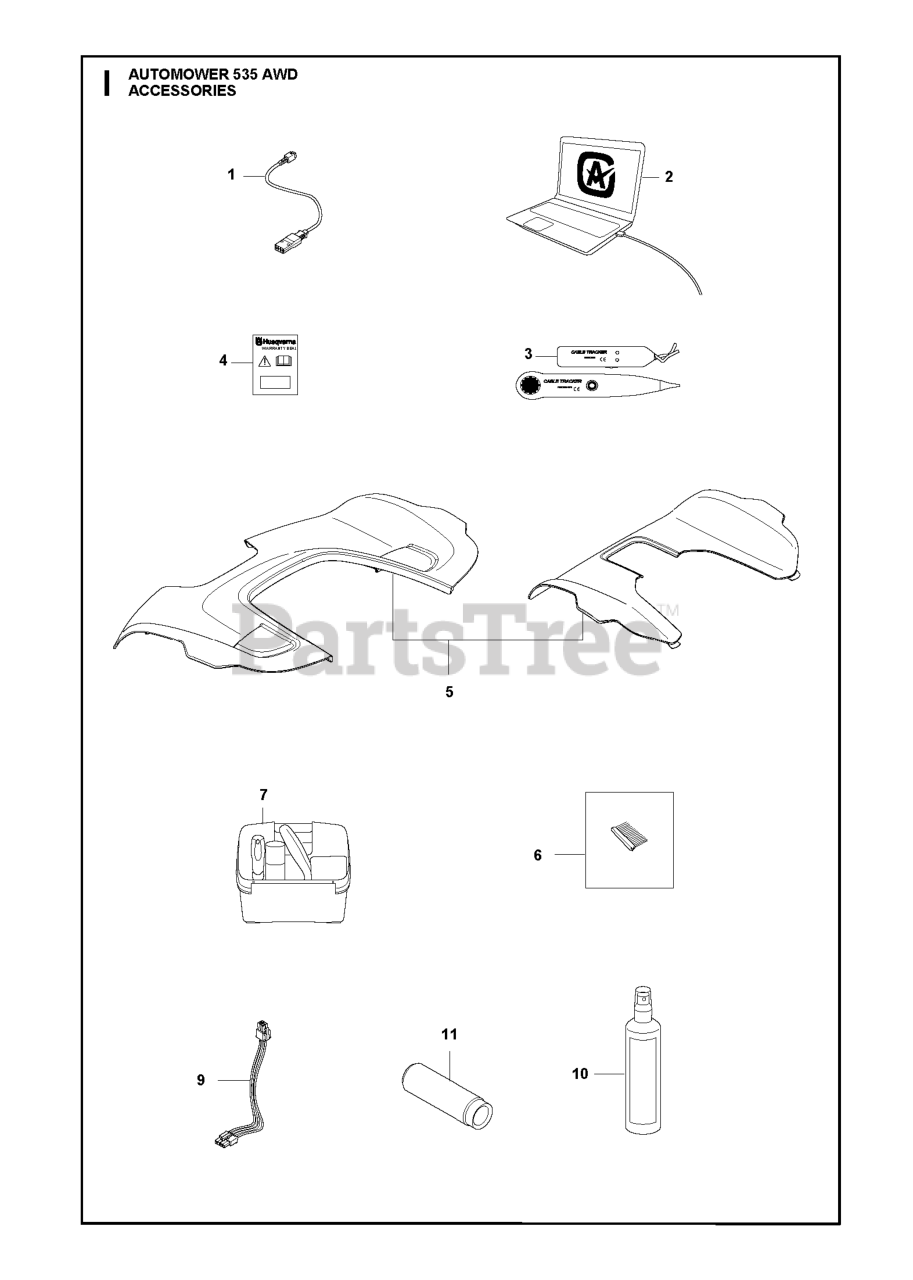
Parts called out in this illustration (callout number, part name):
1	CABLE ASSY QUICK CHARGER
3	TEST EQUIPMENT
4	LABEL WARRANTY SEAL DEALER
6	BRUSH WITH CARTON
7	CLEANING AND MAITENANCE KIT AM
9	WIRING ASSY BATTERY CABLE
10	AUTOMOWER ACCY
11	FLYWHEEL KNOCKER-FINE THREAD
